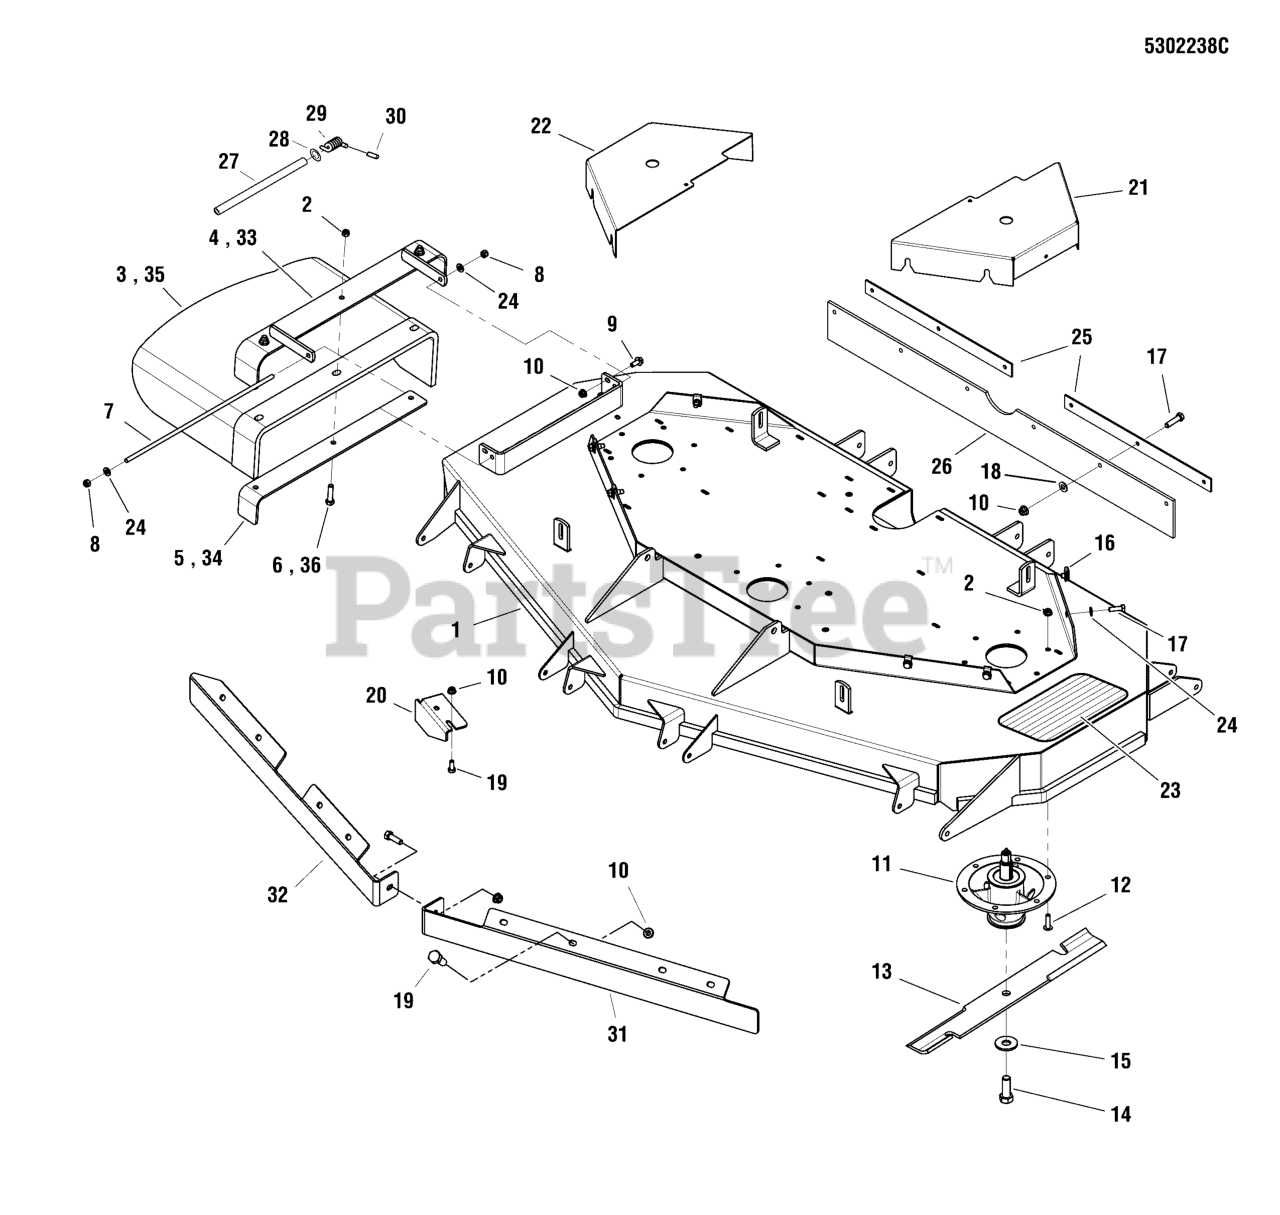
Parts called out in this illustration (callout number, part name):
1	DECK SHELL W/ DECALS, F800X/61 (5407677B)
1	DECK SHELL W/ DECALS, 61, F800XCE (5406817B)
2	NUT, 3/8-16 HEX NYLOCK FLANGE
3	CHUTE, DISCHARGE, BEND RUBBER (SV)
4	WELD, FRAME CHUTE, 61 - BLK
5	SUPPORT, DISCHARGE CHUTE, 61/72 - BLK
6	BOLT, 3/8-16 X 1-1/2" GD5 CZ
7	ROD MOUNT, CHUTE 61"
8	NUT, 5/16-24 HEX NYLON LOCK
9	BOLT, 5/16-18 X 3/4 GD5
10	NUT, 5/16-18 HEX NYLOCK FLANGE
11	SPINDLE ASSM, CAST IRON 8.0-6 BOLT
12	BOLT, 3/8-16 X 1, FLANGE, GD 5, CZ
13	BLADE SET, 61 DECK (3)
14	BOLT, 5/8-11 X 1-3/4 GD8
15	WASHER, BLADE BOLT, 9/16" F436, CZ
16	BODY CLIP, 5/16-18-7GA MATERIAL
17	BOLT, 5/16-18 X 1 GD5 YZ
18	5/16 PUSH-ON NUT RETAINER, STL, CZ
19	BOLT, 5/16-18 X 3/4, CARRIAGE
20	PLATE, DEFLECTOR - BLK
21	GUARD, 61, LH - OUTFRONT - RED
22	GUARD, 61, RH - OUTFRONT - RED
23	SAFETY WALK, 4.00 X 7.50
24	WASHER, 5/16" SAE
25	PLATE, SUPPORT, S800X - RED
26	FLAP, STRIPER, 61 DECK
27	TUBE, 1/2 X 3/8 X 10.75 BLACK POLY
28	WASHER, 5/16 FENDER
29	SPRING, TORSION
30	CAP, PROTECTOR, .120 ID
31	BAFFLE, BLOWOUT, 61 ICD, LH - BLK
32	BAFFLE, BLOWOUT, 61 ICD, RH - BLK
33	MOUNT
34	SUPPORT, DISCHARGE CHUTE - BLK
35	CHUTE, RUBBER DISCHARGE (5413499)
36	BOLT, 3/8-16 X 1-1/2, CARRIAGE, GD5, CZ
